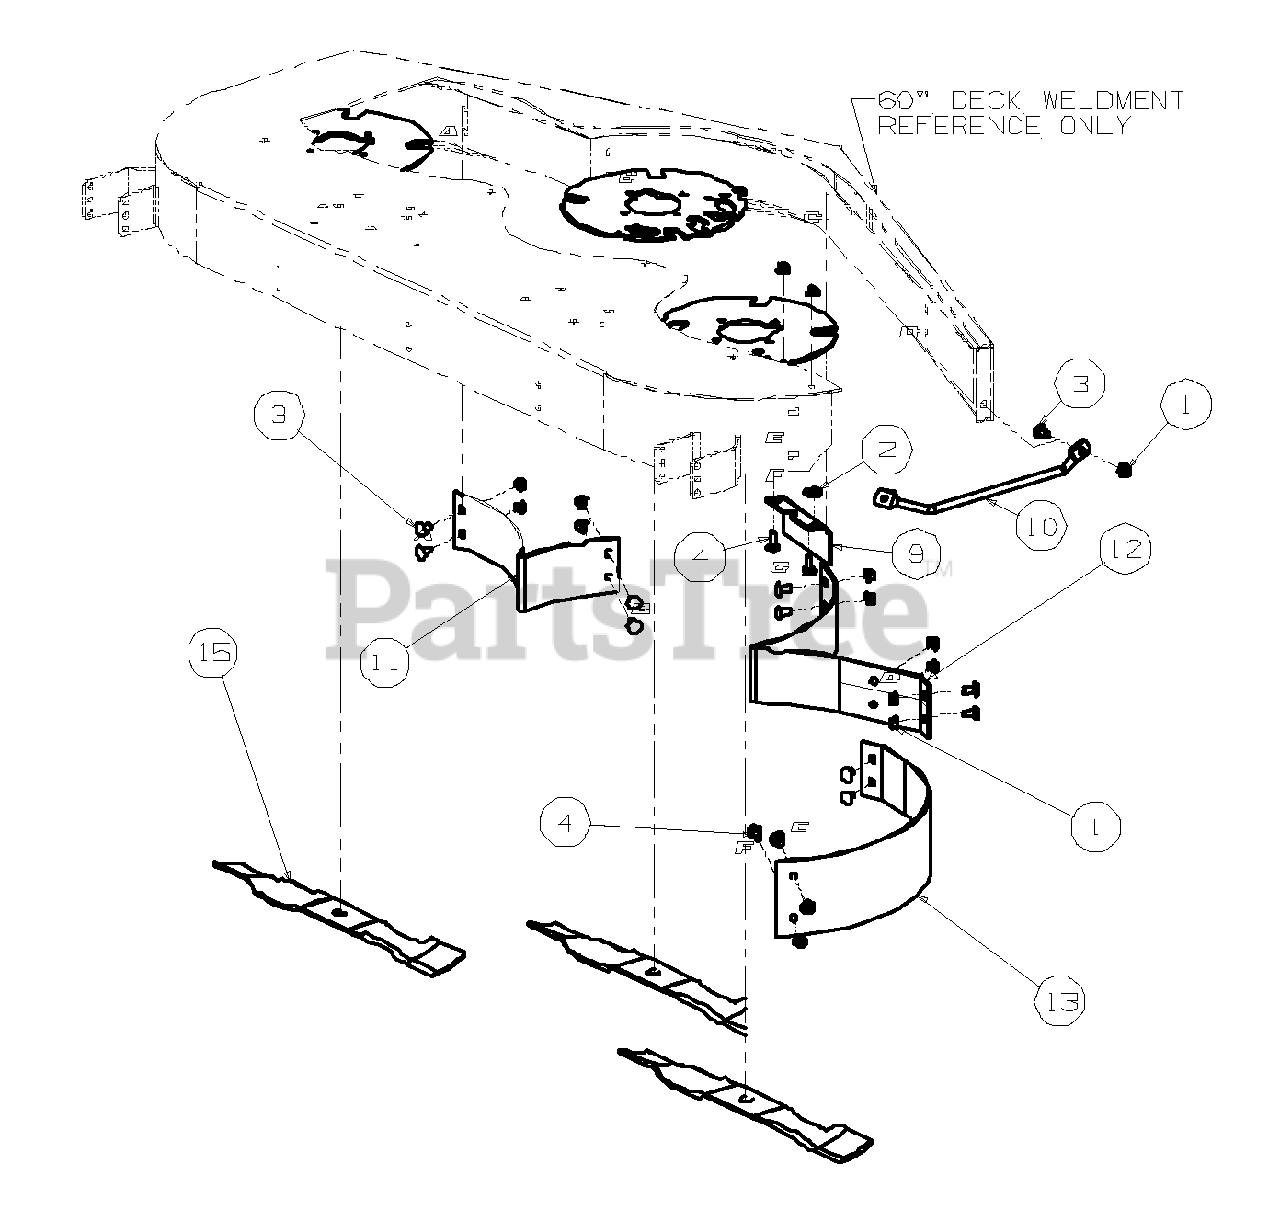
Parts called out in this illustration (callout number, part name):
1	NUT:HEX 3/8-16 FLG LOCK
2	WASHER:IDLER
3	BOLT:CARR 3/8-16 X .75 LG
4	BOLT:CARR 3/8-16 X 1.0 LG
9	BRKT:CHUTE:FAB DECK
10	GUARD:FINGER:FAB DECK
11	BFL:MULCH:FAB 60 LH
12	BFL:MULCH:FAB 60 CENTER
13	BFL:MULCH:FAB 60 RH
15	BLADE:21.0:MULCH:0.756 ID
